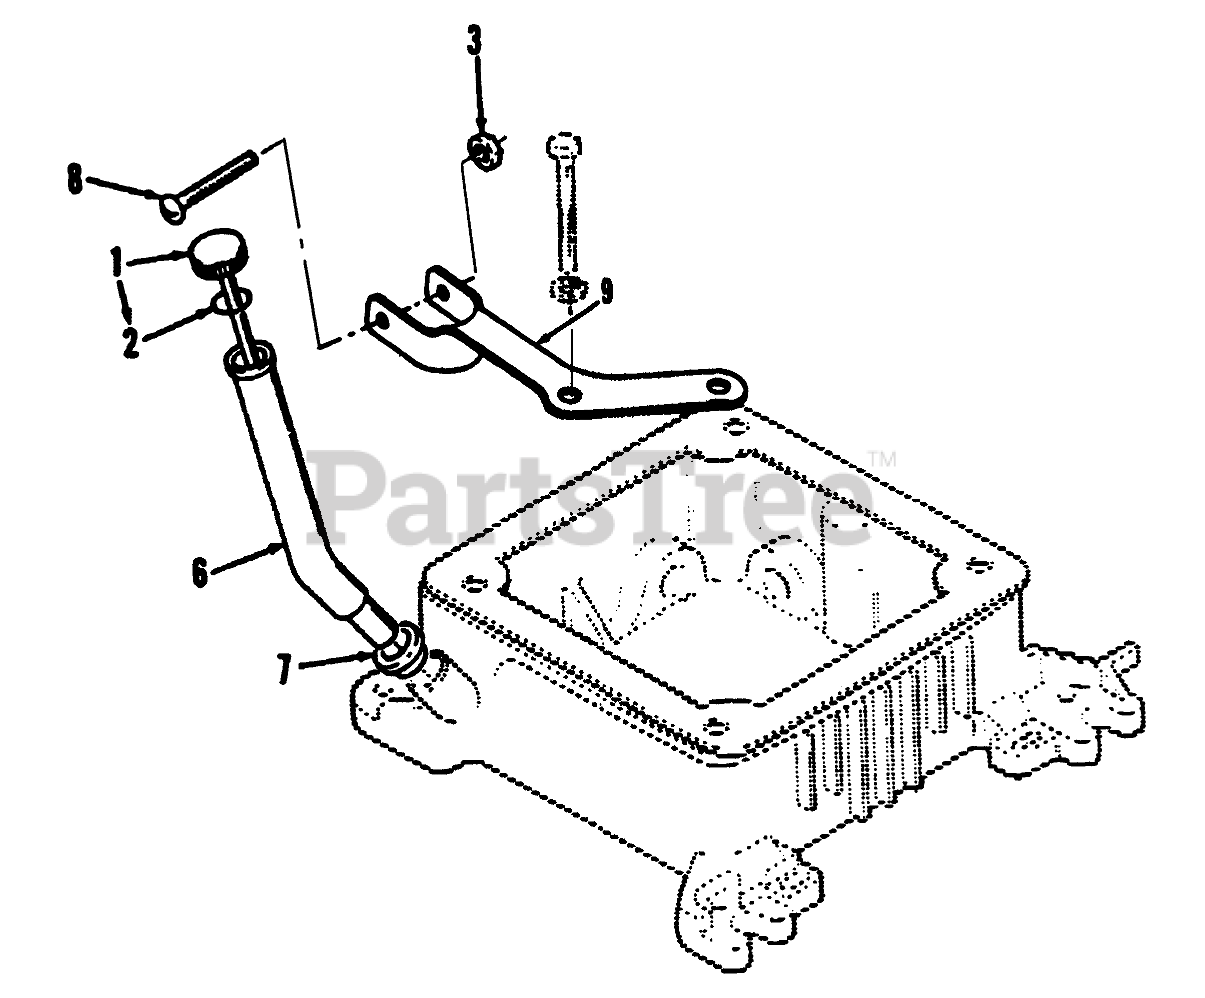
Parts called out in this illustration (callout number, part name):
1	Cap & Indicator-Oil Fill (Includes) O-Ring) Dipstick-1.75 Quart Capacity Specifies Pints-16.27" Long
2	O-Ring
3	NUT - SPEED
6	Tube-Oil Fill
7	Seal
8	SCREW - PAN HEAD
9	BRACKET-FILL TUBE
